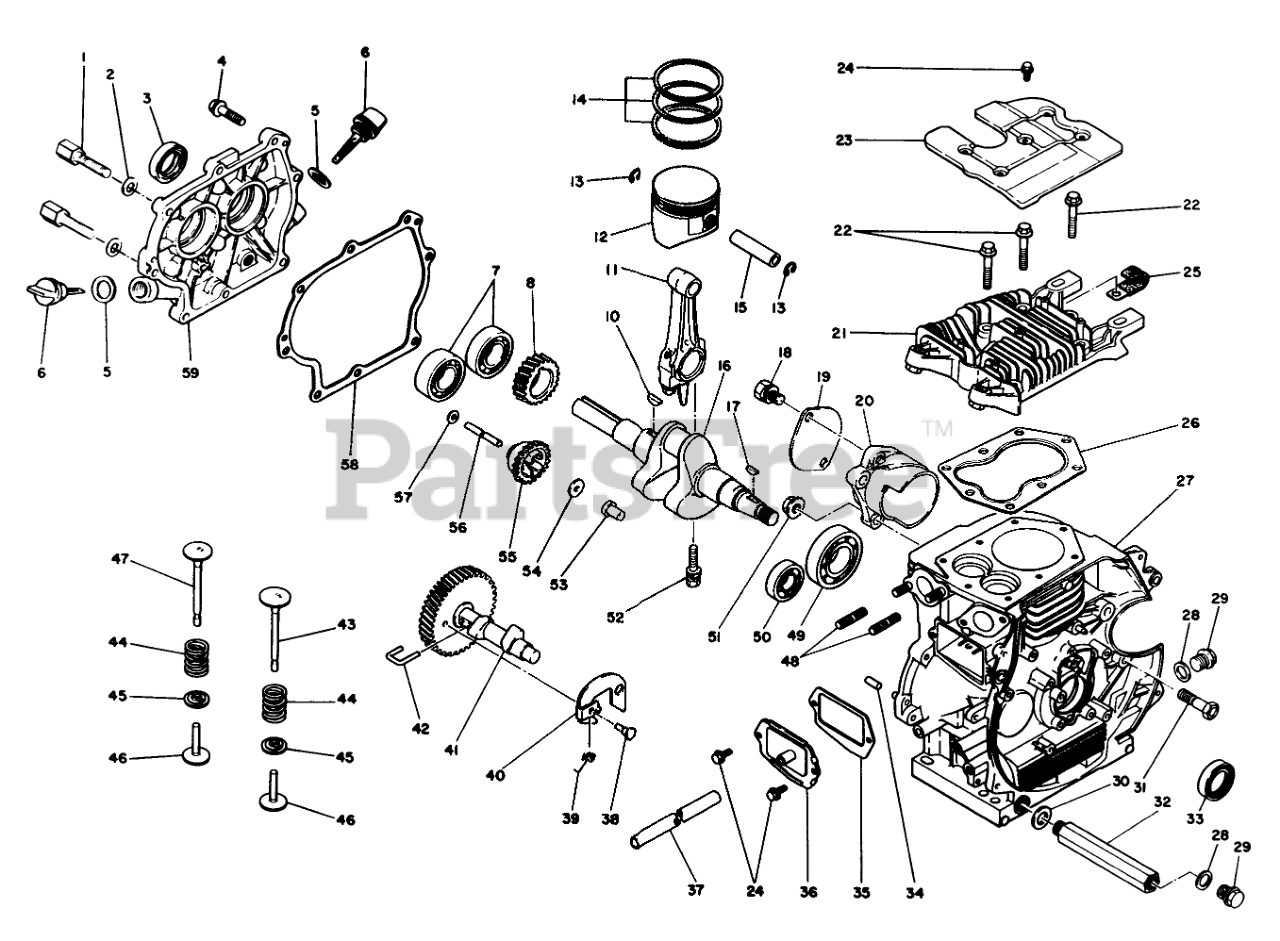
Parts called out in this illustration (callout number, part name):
2	WASHER
3	OIL SEAL
5	GASKET
6	Gauge-Oil (Incl. Ref. #5)
7	BEARING
8	CRANKSHAFT GEAR
11	Connecting Rod Assembly (Std.)(Incl. Ref #52)
12	Piston Assembly (Std.)(Incl. Ref. #15)
14	PISTON RING SET
15	PIN - PISTON
16	CRANKSHAFT
18	BOLT & WASHER
19	COVER
20	BRACKET
21	CYLINDER HEAD
23	COVER-HEAD
25	CLAMP
26	HEAD GASKET
27	Cylinder Block Assembly (Incl. Ref. #34 & 48)
28	GASKET
29	DRAIN PLUG
30	GASKET
32	NIPPLE
33	OIL SEAL
35	GASKET=BRTHR
36	BREATHER VALVE ASM
37	BREATHER TUBE
39	SPRING
40	FLYWEIGHT
41	Camshaft Assembly (Incl. Ref. #38, 39, 40 & 42)
43	INTAKE VALVE
44	VALVE SPRING
45	RETAINER VALVE
46	TAPPET
47	EXHAUST VALVE
49	BEARING
50	BEARING
51	Nut-Flange
52	CONNECTING ROD BOLT
53	SLIDER-GOV
54	SPACER
55	Governor Gear Assembly (Incl. Ref. #53)
56	SHAFT-GOV.
57	WASHER
58	GASKET
59	COVER-CRANKCASE
